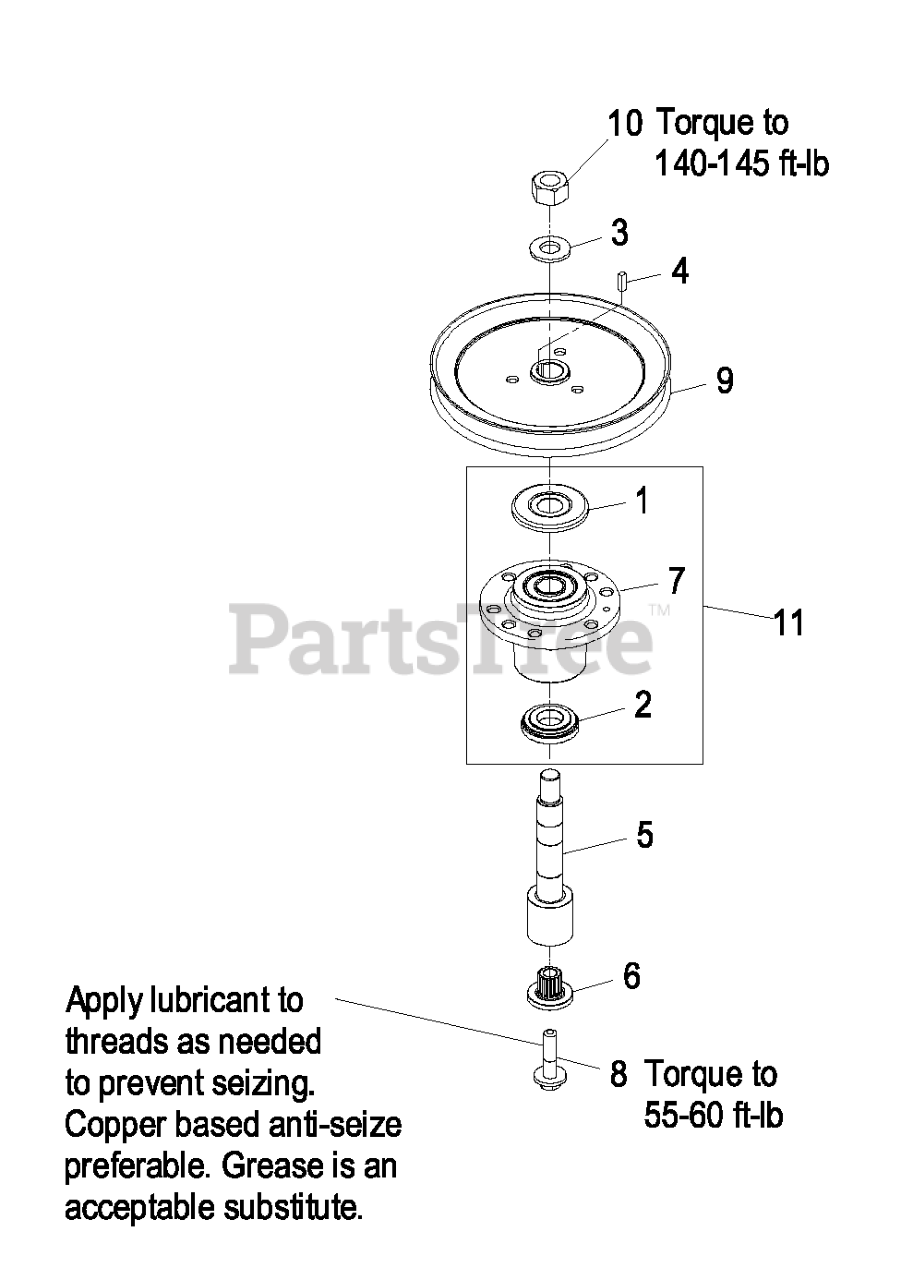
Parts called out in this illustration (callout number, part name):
1	GUARD-BEARING, TOP
2	SPACER-GUARD, BOTTOM
5	KIT, SPLINED SPINDLE 103-
6	BUSHING,SPLINED
8	SCREW,SEMS 1/2-20 X 2.19
9	SHEAVE,BLADE DRIVE 8.74
11	KIT, CUTTER HOUSING
